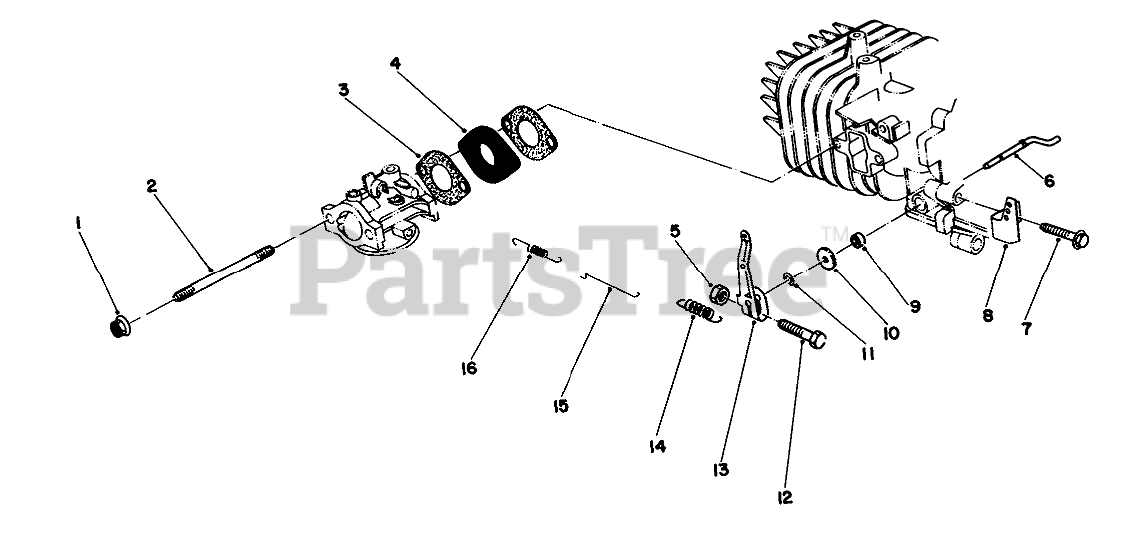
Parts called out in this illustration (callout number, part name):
1	M6 X 1 LOCKNUT
2	Stud-Bolt-Carburetor
3	GASKET-CARB
4	CARB. INSULATOR
6	Shaft-Govemor
8	Bracket-Governor Spring
9	SEAL-OIL
10	WASHER
11	E-RING
13	Lever-Throttle Control
14	SPRING
15	ROD-CARBURETOR
16	Spring-Governor
